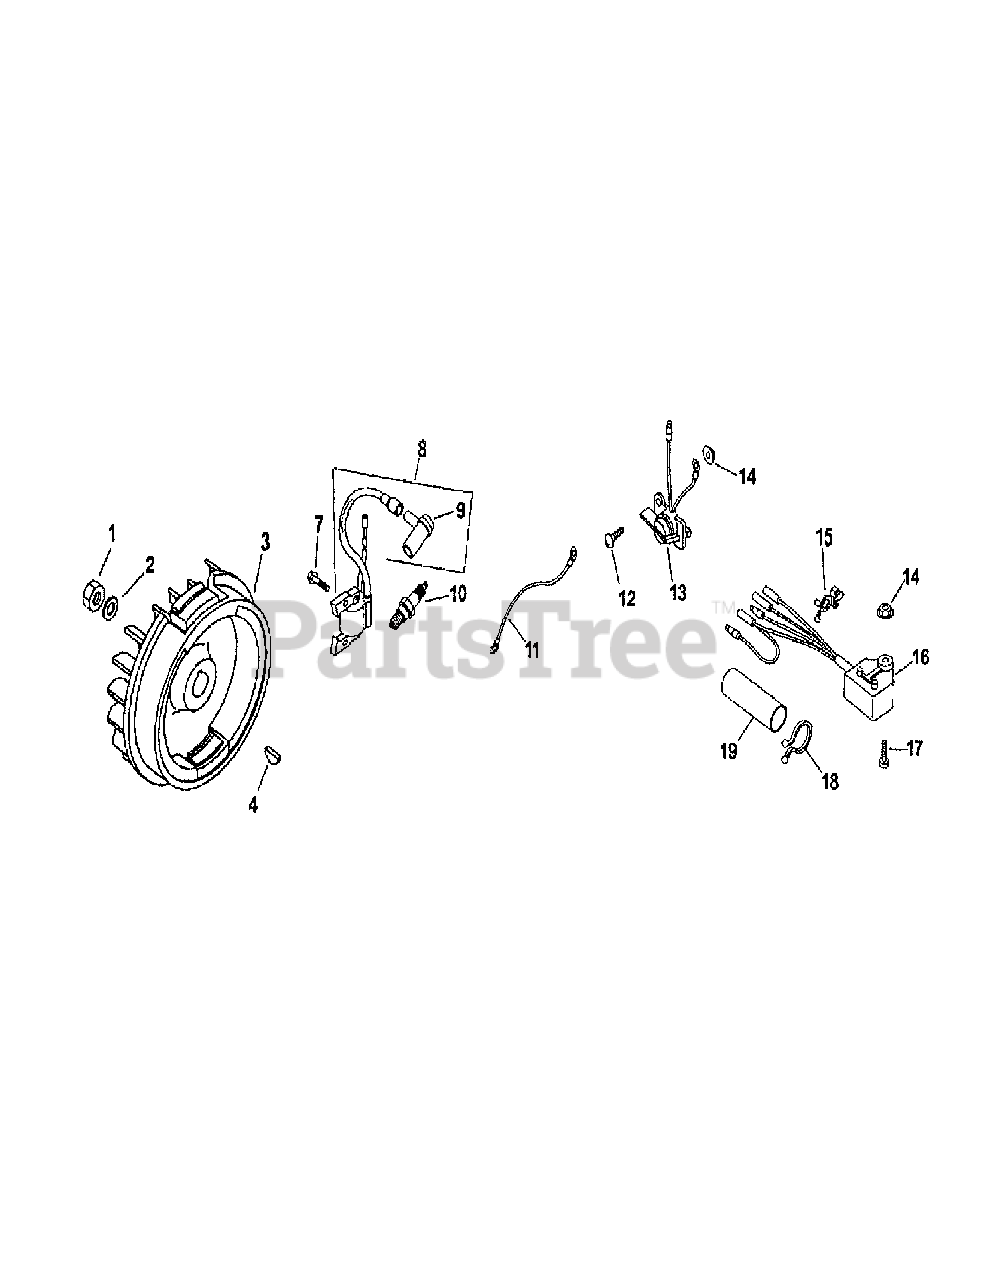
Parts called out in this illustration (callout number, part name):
1	Nut, Flywheel
2	Washer, Flywheel
3	Flywheel
4	Key, Flywheel
8	Ignition Module
9	Cap, Spark Plug
11	Ground, Ignition
12	Screw, Stop Switch
19	Sleeve, Wiring
